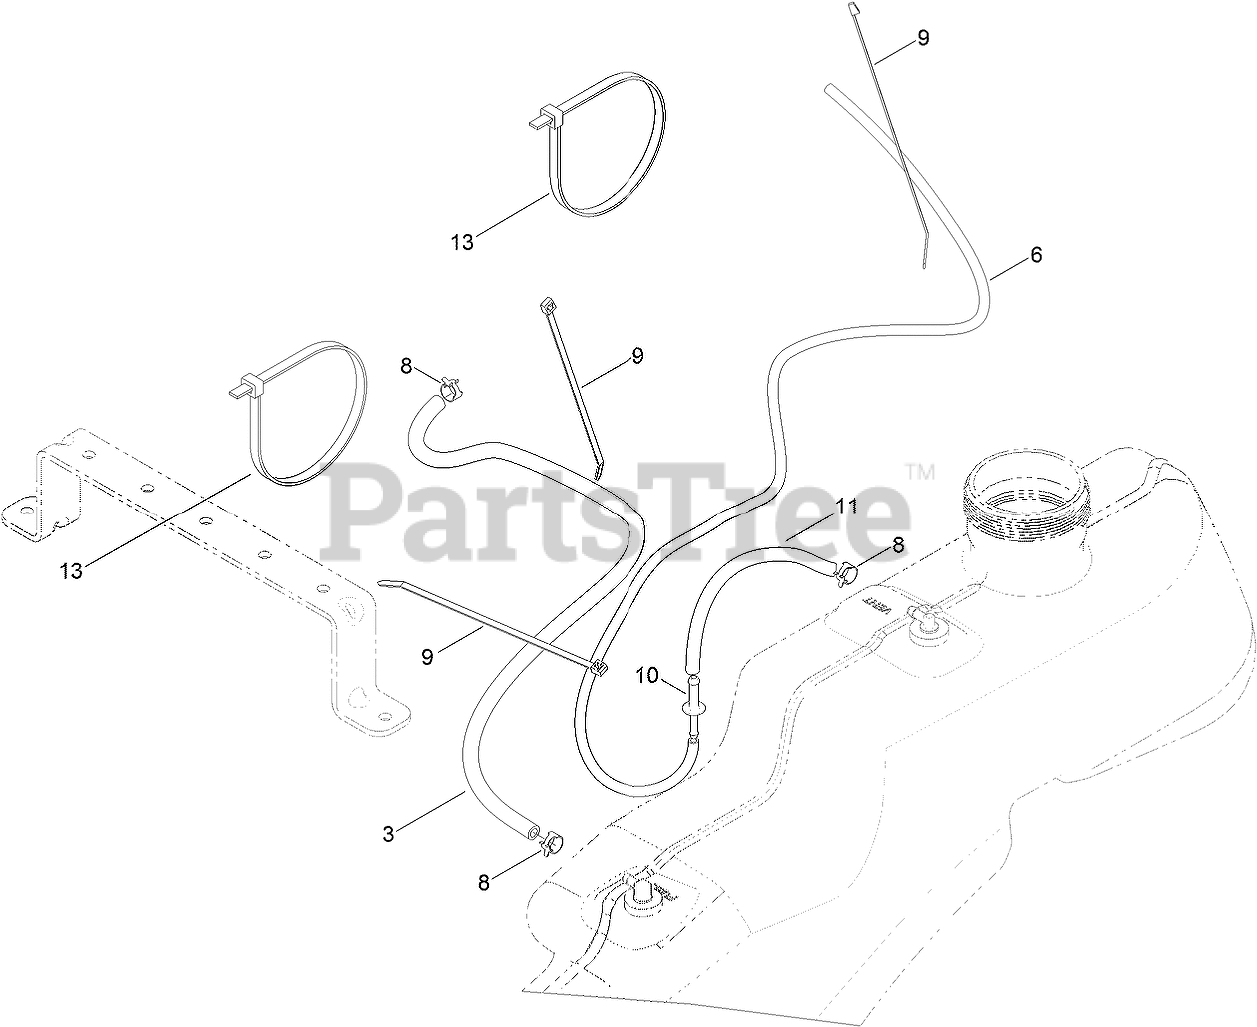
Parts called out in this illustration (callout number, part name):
3	HOSE-FUEL
6	HOSE-FUEL
8	CLAMP-HOSE
9	TIE-CABLE
10	ADAPTOR-ORIFICE
11	HOSE-FUEL
13	TIE-CABLE
